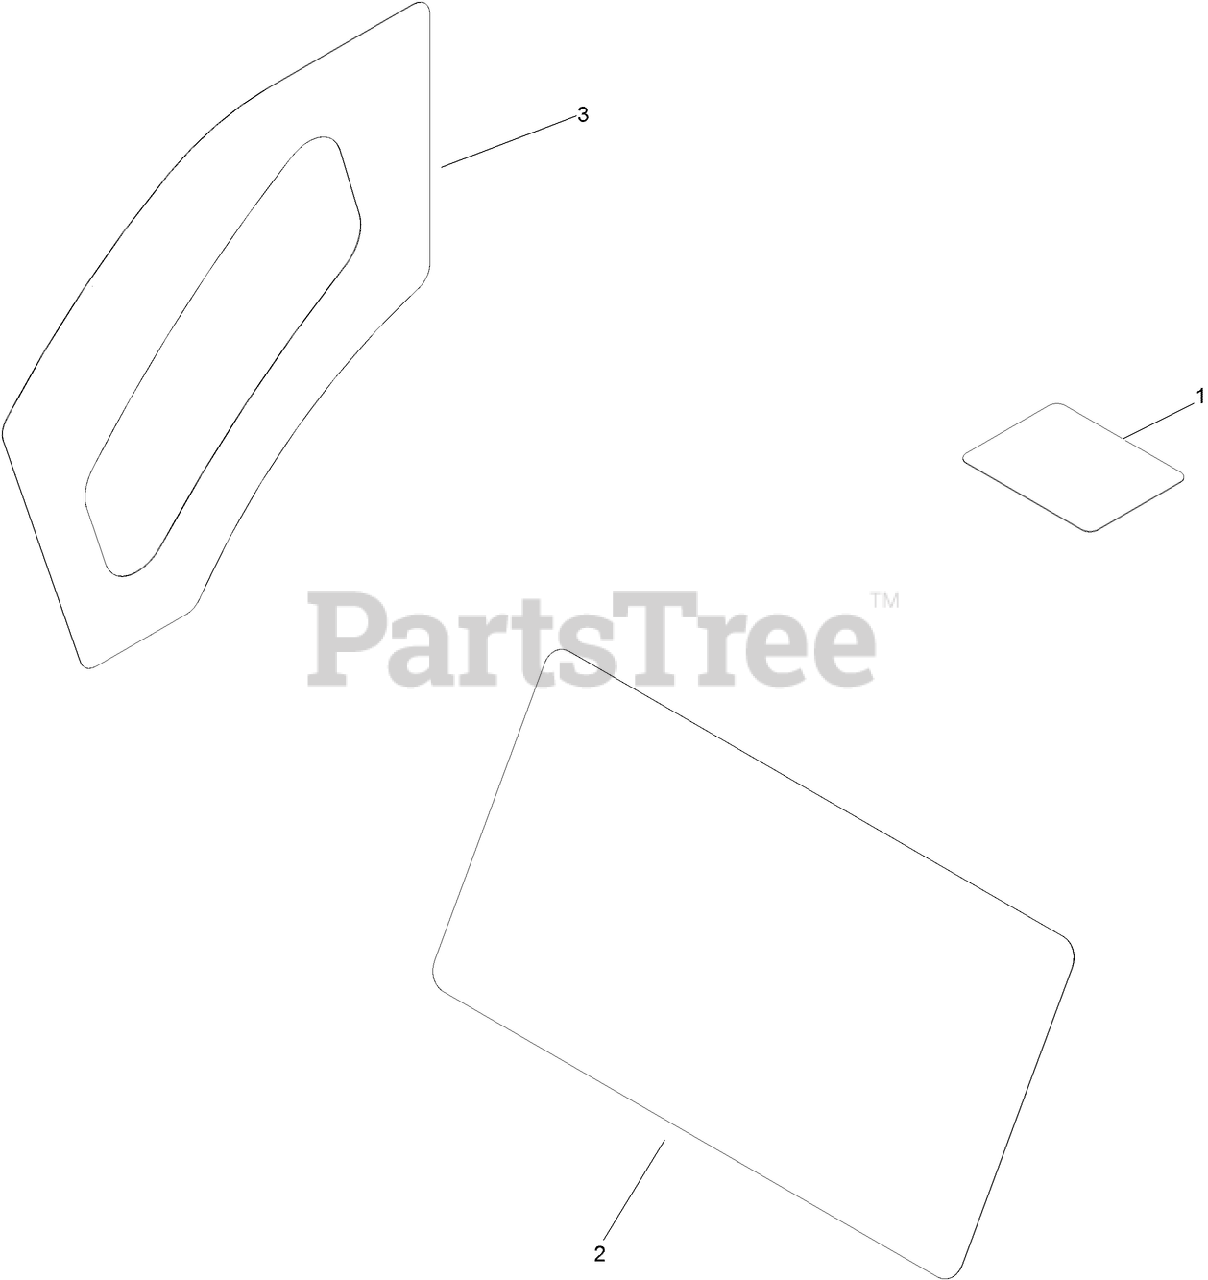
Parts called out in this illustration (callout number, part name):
1	DECAL-MAINTENANCE
2	DECAL-SMART SPEED
3	DECAL-HOC
